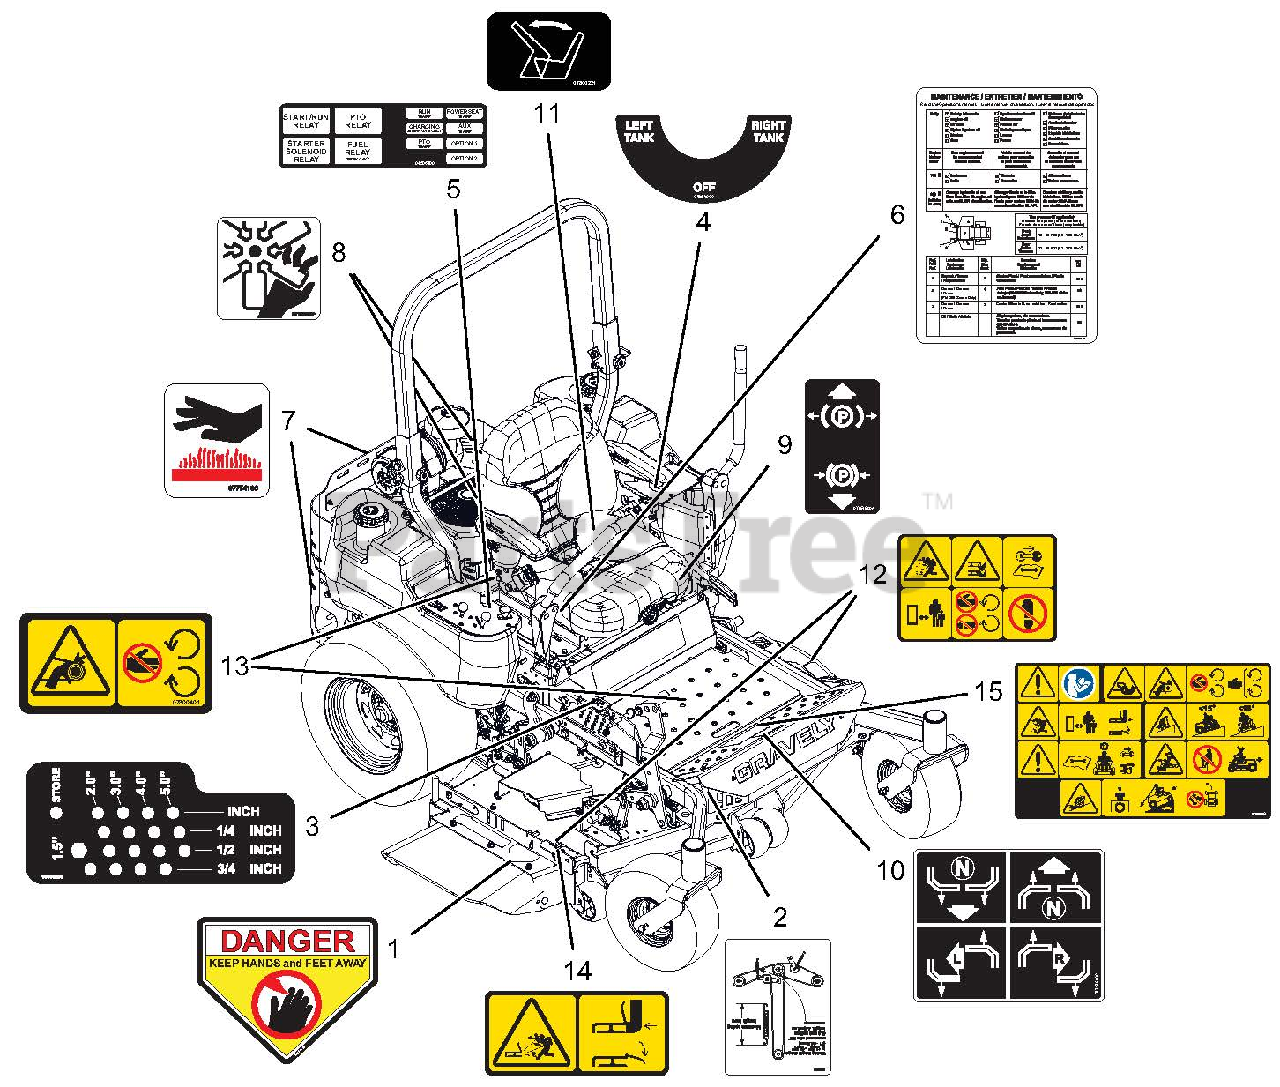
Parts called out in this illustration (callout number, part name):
1	DECAL, DANGER
2	DECAL, BELT ROUTING
3	DECAL, HEIGHT OF CUT
4	DECAL, FUEL VALVE
5	DECAL, FUSE BOX
6	DECAL, MAINTENANCE
7	DECAL HOT SURFACE
8	DECAL, DANGER - FAN
9	DECAL, PARKING BRAKE LEVER
10	DECAL, INSTRUCTIONAL - STEERING
11	DECAL, SEAT RELEASE
12	DECAL, SAFETY - MOWER DECK
13	DECAL, SAFETY - GUARDING
14	DECAL, SAFETY - DECK GUARDING
15	DECAL, MAIN SAFETY, COMMERCIAL
